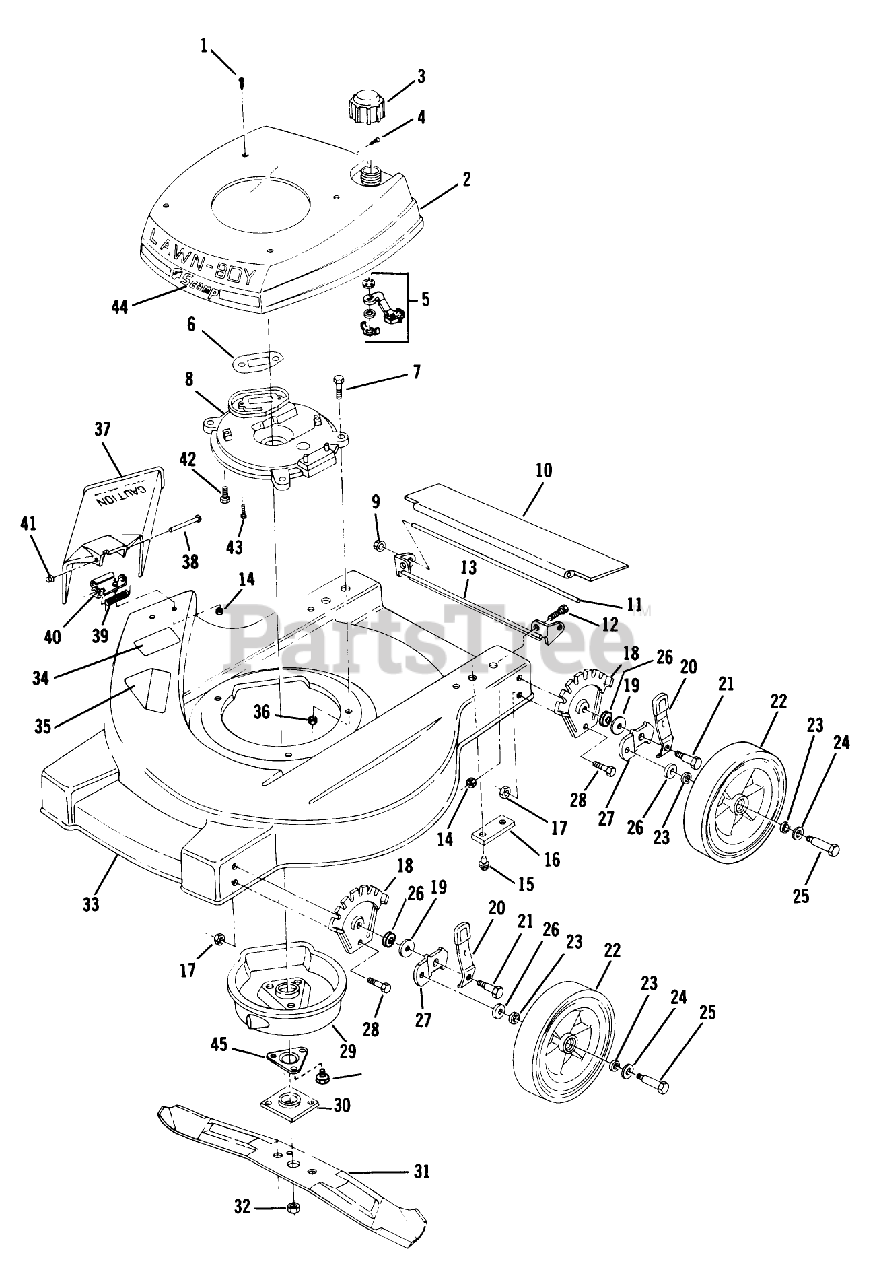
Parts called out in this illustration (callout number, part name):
1	SCREW LAWRENCE
3	FUEL CAP & INSERT
4	SCREW S
7	SCREW-HH
8	PLATE,MUFFLER F
10	TRAILING SHIELD
13	BRACKET (12)
14	LOCKNUT E
15	SCREW
17	LOCKNUT
19	WASHER
20	KNOB & SPRING
21	BOLT
23	WASHER
24	SPACER
25	BOLT WHEEL
26	WASHER WROUGHT
30	PLATE AND COLLAR ASM
32	NUT-BLADE
36	NUT-LOCK F
37	CHUTE DEFLECTOR AY
38	PIN
40	HINGE & SCREW ATA
43	SCREW V
45	SUPPORT F
46	SCREW
